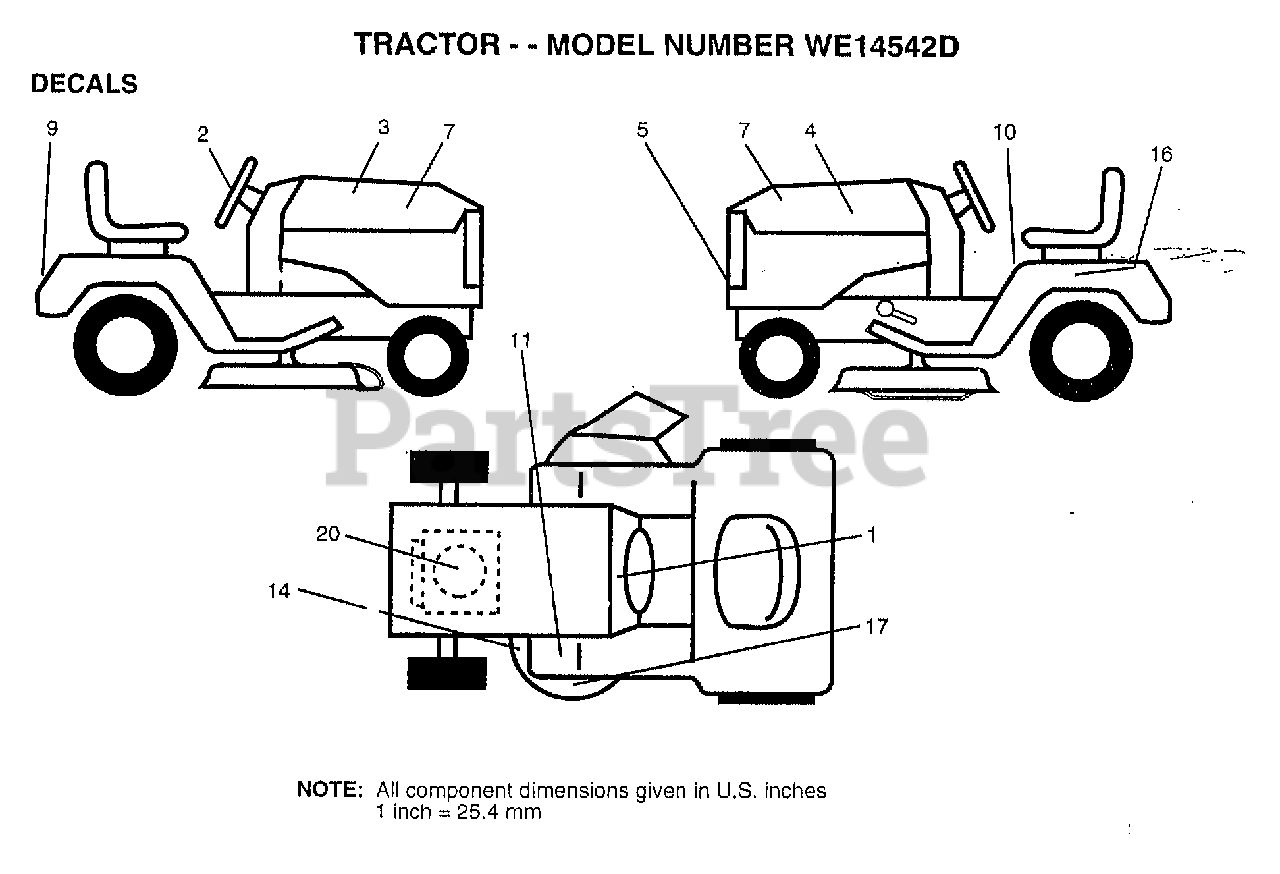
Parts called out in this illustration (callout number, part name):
1	"DECAL DASH,OPER."
2	"DECAL INS,STRG WH"
3	"DECAL HOOD,RH"
4	DECAL HOOD LH
5	"DECAL GRILLE,LENS"
7	"DECAL PANEL,SIDE"
9	DECAL-FENDER
10	"DECAL DANGER,FEND"
14	DECAL
16	DECAL.BATRY.3-3908
20	DECAL, ENGINE
